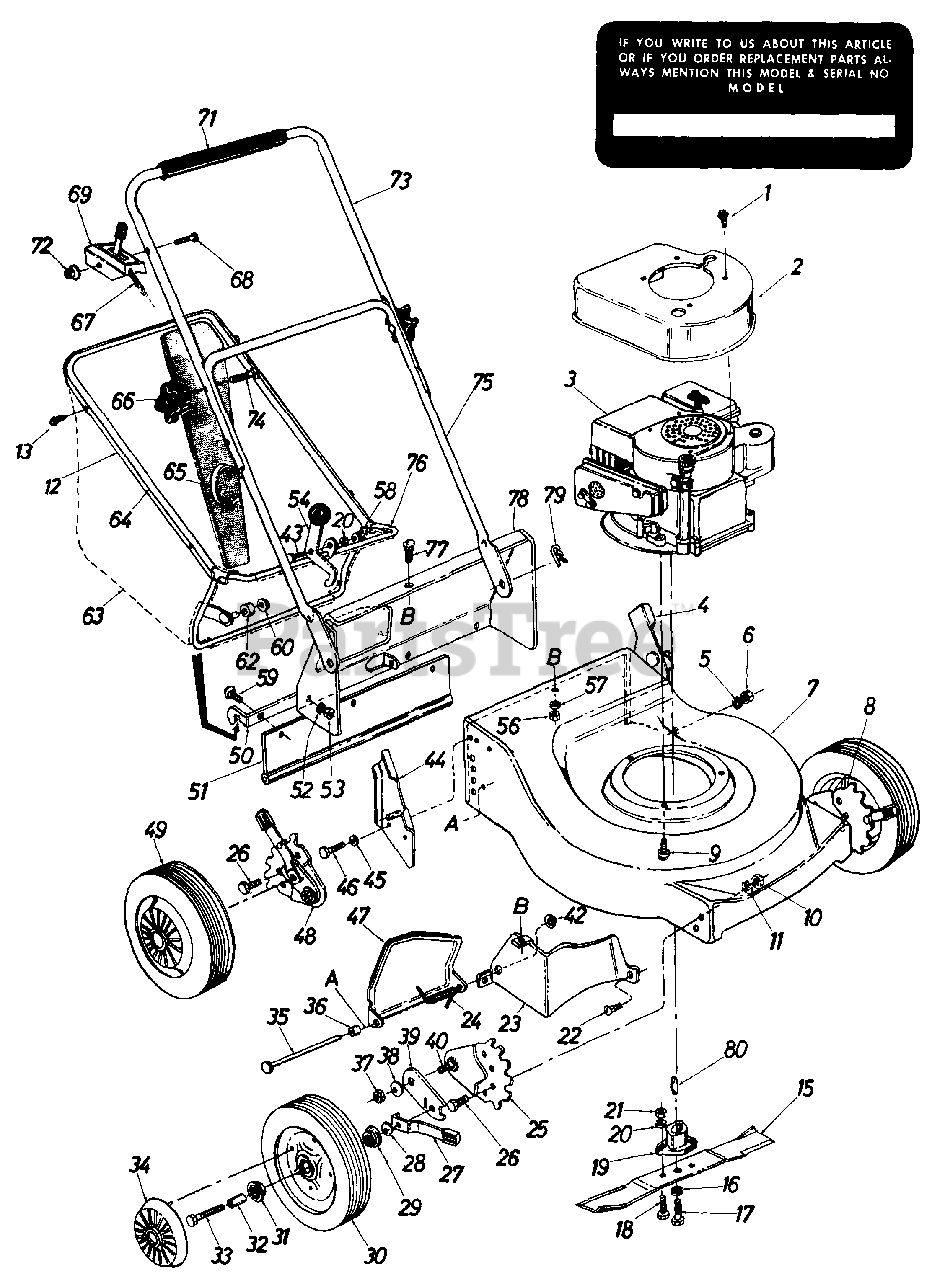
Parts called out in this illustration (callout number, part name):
1	Hex Wash. Hd. Self-Tap Scr. #8 x .38" Lg.
2	Engine Shroud - Metal
3	Engine
4	Handle Mount Brkt. - L.H.
5	L-Wash. 1/4" I.D.
6	Hex Nut 1/4-20 Thd.
7	20" Deck Ass'y.
8	Height Adjuster Ass'y. Comp. - L.H.
9	Hex Wash. Hd. Self-Tap Scr. 3/8-16 x .88" Lg.
10	Hex Nut 3/8-16 Thd.
11	L-Wash. 3/8" I.D.
12	Grass Catcher Top Cover
13	Hex AB-Tap Scr. #10 x 1/2 Lg.
15	20" Blade
16	L-Wash. 3/8" I.D. Heavy Duty
17	Hex Bolt 3/8-24 x 1.50" Lg. (Grade 5)
18	Hex Bolt 5/16-24 x 1.00" Lg. (Grade 5)
19	Blade Adapter Kit
20	L-Wash. 5/16" I.D.
21	Hex Nut 5/16-24 Thd.
22	Carriage Bolt 1/4-20 x .50" Lg.
23	Rear Baffle
24	Torsion Spring
25	Index Plate
26	Hex Sems Bolt 3/8-16 x .62" Lg.
27	Spring Lever With Knob
28	Belleville Wash.
29	Ball Bearing
30	Front Wheel Ass'y. Comp. 8 x 1.75
31	Ball Bearing
33	Hex Bolt 3/8-16 x 2.0" Lg.
35	Hinge Pin .25" Dia. x 7.88" Lg.
36	Spacer .262 I.D. x .31 O.D. x .58" Lg.
37	Hex Cent. L-Nut
38	Belleville Wash.
39	Pivot Bar
40	Shoulder Bolt
42	Cap Speed Nut 1/4" Rod
43	Shld. Bolt .437" Dia. x .180" Lg.
44	Handle Mount Brkt. - R.H.
45	Fl-Wash. .281" I.D. x .50" O.D. x .063
46	Hex Wash. Hd. Self-Tap Scr. 1/4 x .62" Lg.
47	Chute Door
48	Height Adjuster Ass'y. Comp. - R.H.
49	Rear Wheel Ass'y. Comp. 8 x 1.75
50	Grass Catcher Hitch Brkt.
51	Rear Protective Flap Ass'y.
52	Fl-Wash. .285 I.D. x 1.25" O.D.
53	Hex Sems Nut 1/4-20 Thd.
54	Cam Lever Ass'y.
56	Hex Nut 1/4-20 Thd.
57	L-Wash. 1/4" I.D.
58	Hex Nut 5/16-18 Thd.
59	Carriage Bolt 1/4-20 x .75" Lg.
60	Cap Speed Nut 3/8" Rod
62	Plastic Roller
63	Grass Bag
64	Grass Catcher Upper Frame
65	Cable Tie
66	Hand Knob
67	Conduit and Wire
68	Hex Bolt 1/4-20 x 1.50" Lg.
69	Throttle Control Ass'y. Comp.
72	Hex Cent. L-Nut 1/4-20 Thd.
73	Upper Handle (Chrome)
74	Curved Hd. Carriage Bolt 5/16-18 x 1.75" Lg.
75	Lower Handle (Chrome)
76	Lower Grass Catcher Frame Ass'y.
77	Carriage Bolt 1/4-20 x .50" Lg.
78	Rear Deck Section
79	Internal Cotter Pin
80	#6 Hi-Pro Key 5/32" x .62" Dia.
